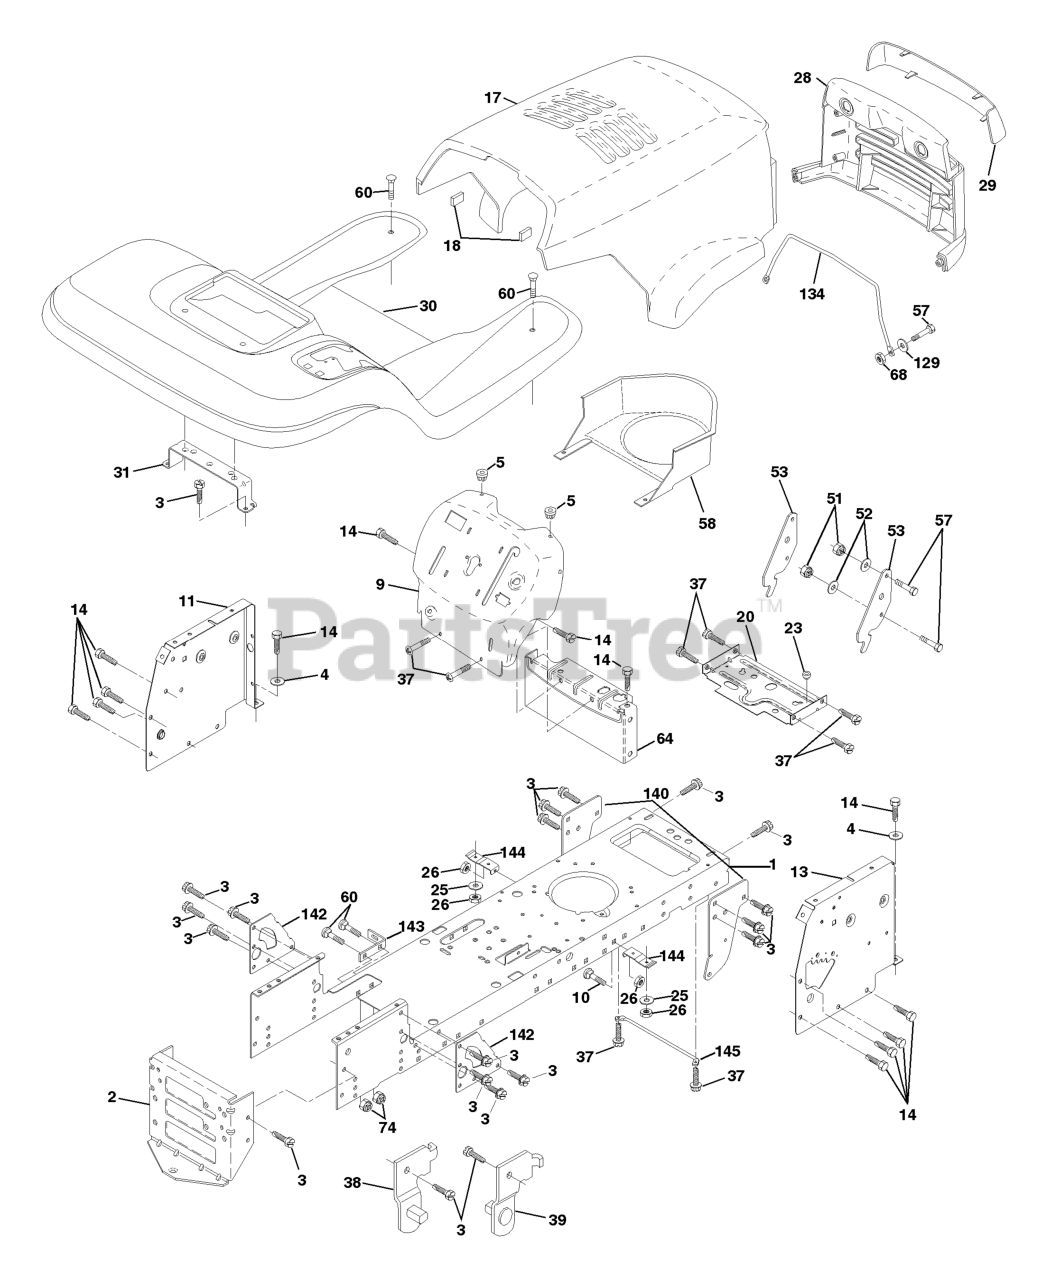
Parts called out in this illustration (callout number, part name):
2	STRETCH DRAWBAR
3	SCREW
4	Washer 13/32 x 3/4 x 16 Ga.
5	BUMPER.RUBBER.HOOD
9	DASH PANEL
10	BOLT D
11	PANEL DASH LH
13	PANEL DASH RH
14	SCREW LT
17	HOOD - LT/YT
18	BUMPER HOOD T
20	PLATE MTG
23	BUSHING.SNAP.NYL.BLK.
25	WASHER
26	NUT
28	GRILLE LT/PL HUSQVARNA
29	LENS LT/PL HUSQVARNA
30	FENDER FOOTREST
31	BRACKET.SUPPORT.FENDER
37	Screw Thdrol 6/16-18 x 1/2 TYT
38	BRACKET LH PIVOT
39	BRACKET RH PIVOT
51	LOCKNUT.NYLOC.1/4-20
52	WASHER
53	BRACKET PNT PICK OFF LT/PL
57	BOLT
58	AIR DUCT P/L/LT
60	Bolt Rdhd Sqnk 3/8-16unc x 3/4
64	DASH LOWER
68	NUT
129	WASHER
134	ROD SUPPORT HOOD LT/PL HUS.
140	BRACKET SUSPENSION FRONT
142	PLATE REINFORCEMENT
143	BRACKET, SWAY BAR
144	BRACKET FOOTREST
145	ROD PIVOT CHASSIS/HOOD
